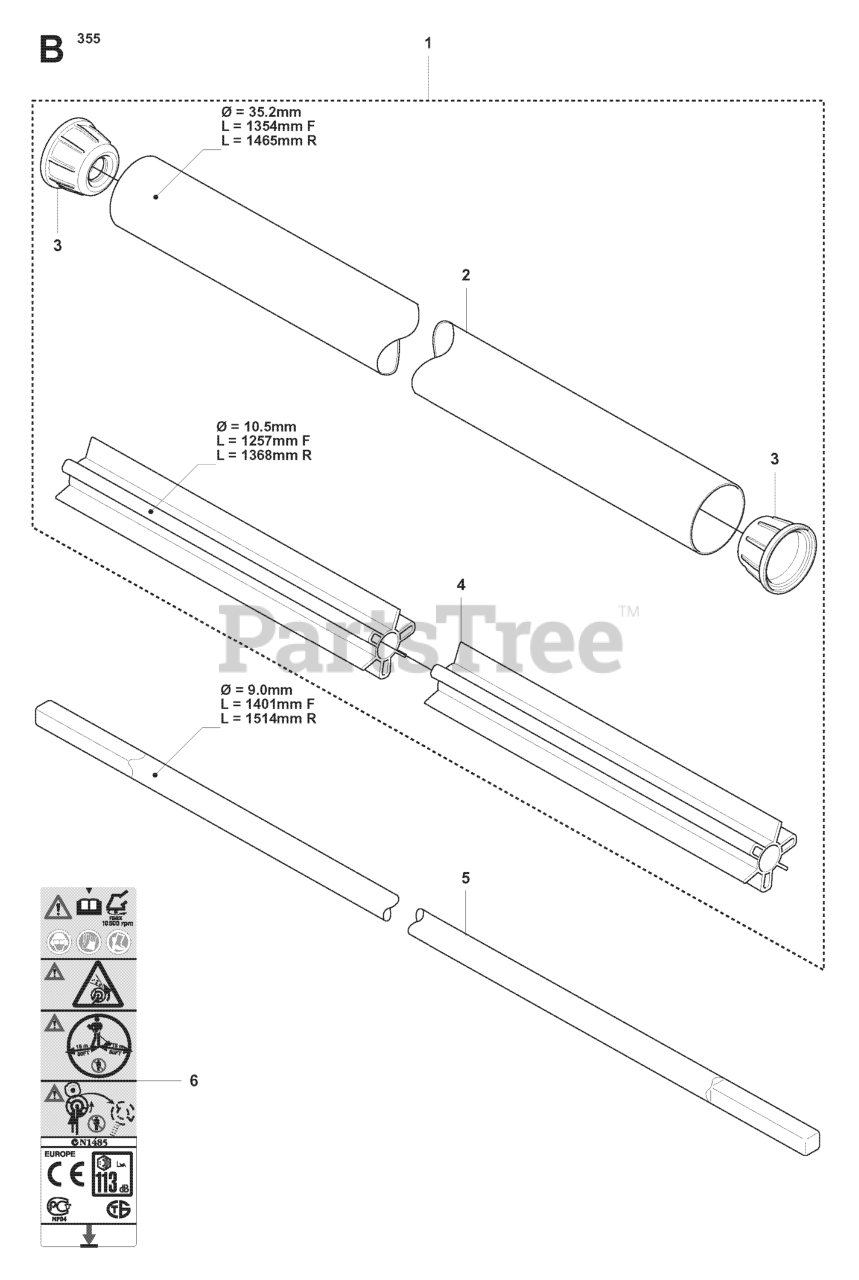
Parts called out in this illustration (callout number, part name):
1	TUBE ASSY
2	TUBE
3	RP SPACER
4	%BEARING SHAFT
4	RP BEARING SHAFT
5	DRIVE SHAFT
